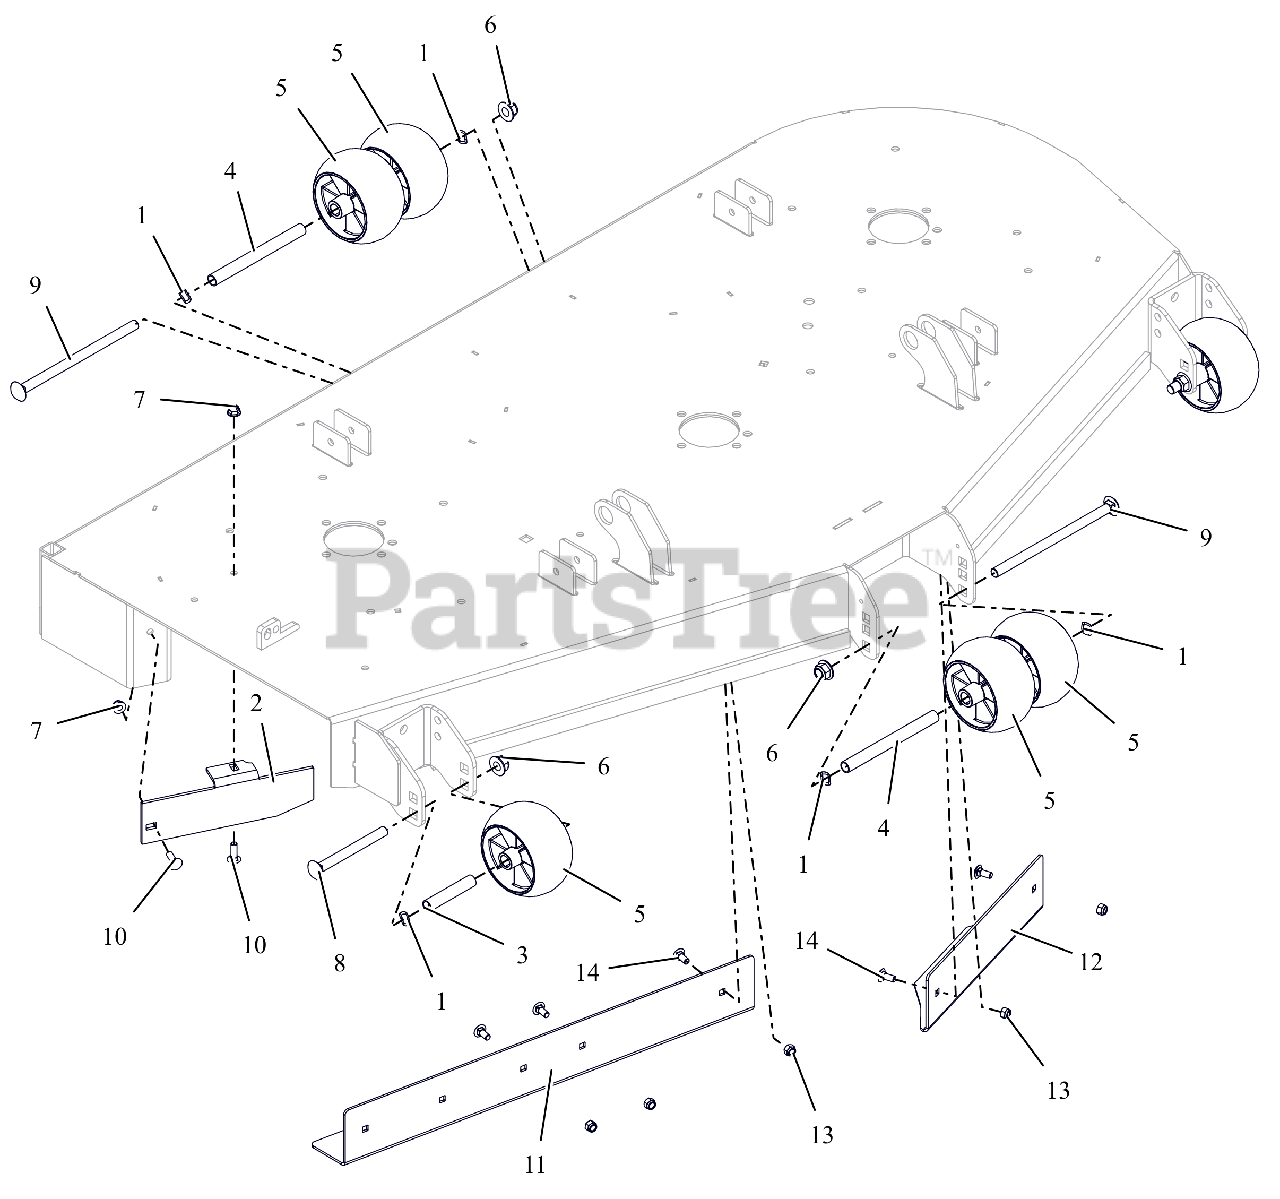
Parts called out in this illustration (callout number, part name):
1	WAVE WASHER .531X.781X.125FH
2	60" DISCHARGE BAFFLE - RED
3	SPACER, .510X.625X3.35
4	SPACER, .510X.625X6.50
5	ANTI-SCALP WHEEL - 5X3 CTR
6	NUT,NYL-FLG .50-13 GF ZCC
7	NUT,NYL-FLG .31-18 GF ZCC
8	BLT, RHSN .50-13X5.00 G5 ZCC
9	BLT, RHSN .50-13X8.50 G5 ZCC
10	BLT,RHSN .31-18X1.00 G5 ZCC
11	BAFFLE, 60" RH VACUUM (RED)
12	BAFFLE, 60" LH VACUUM (RED)
13	NUT,NYL .31-18 G5 ZCC
14	BLT,RHSN .31-18X.75 G5 ZCC
